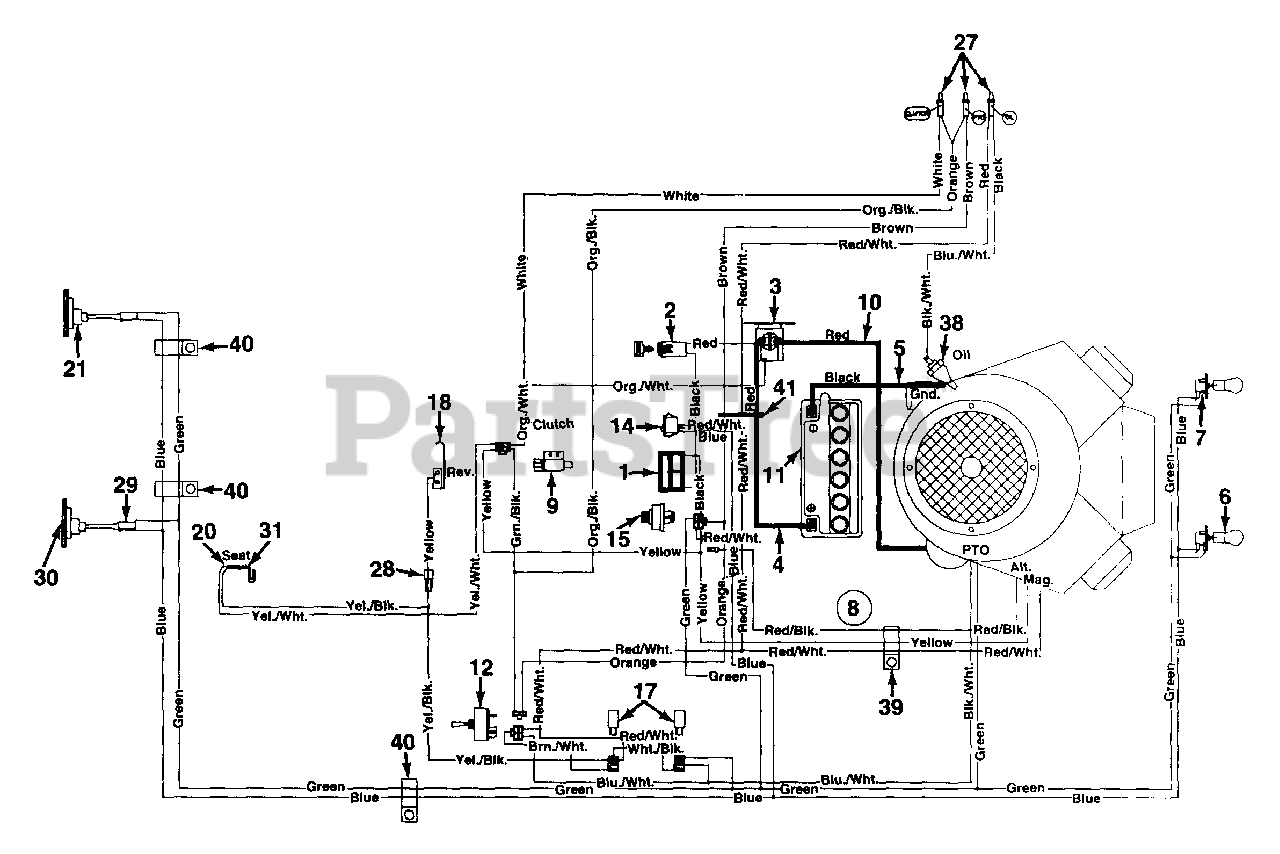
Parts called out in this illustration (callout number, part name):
1	Ammeter
2	Fuse 20 Amp
3	Solenoid
4	Wire
5	6 Ga. Red Wire 20" Lg.
6	Bulb
7	Socket
8	Wire Harness
9	Safety Switch (Clutch)
10	6 Ga. Black Wire
11	Battery
12	Switch (PTO)
14	Light Switch
15	Ignition Switch
17	Relay
18	Spring Lever
20	Safety Switch (Seat)
21	Taillight
27	Bulb
28	Transmission Ext. Wire
29	Taillight Harness
30	Bulb
31	Safety Switch (Seat)
38	Oil Pressure Switch
39	Clamp 9/16" Dia.
40	Clamp 5/16" Dia.
41	Cable Tie
